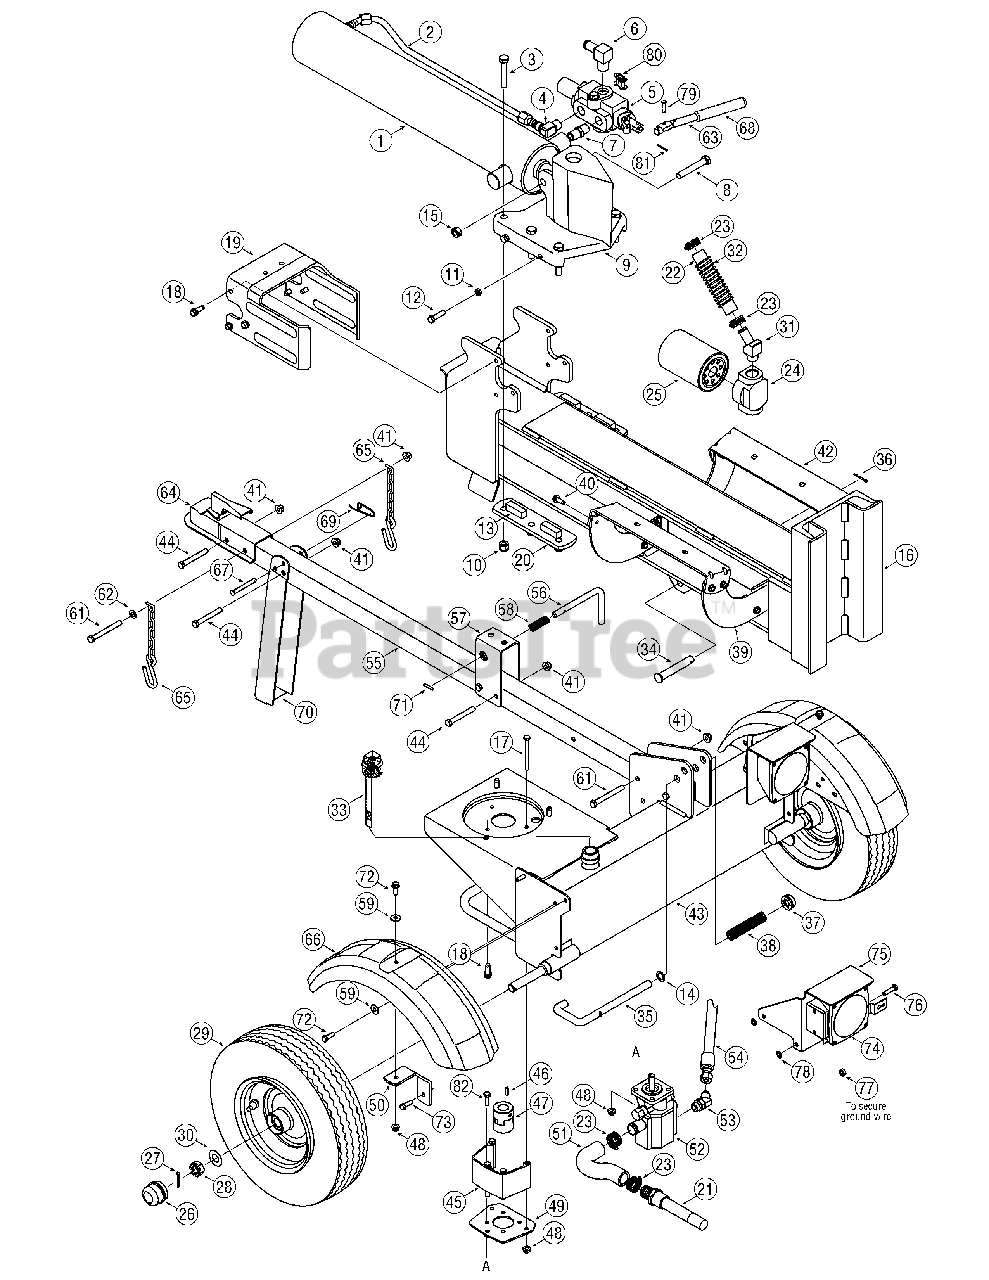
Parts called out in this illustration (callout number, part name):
1	Hydraulic Cylinder 718-0769A
1	Kit Seal 4.5" for XINGHUI cylinder 718-0769A
1	Kit Seal 4.5" for ENERGY cylinder 718-0769A
2	Hydraulic Tube
3	Hex Cap Screw 1/2-20 x 2.75
4	90 Degree Solid Adapter
5	Control Valve
6	Return Elbow
7	Nipple Pipe 1/2-14
8	Hex Cap Screw 1/2-13 x 3.25
9	Wedge Assembly
10	Hex Lock Nut, 1/2-20
11	Hex Jam Nut 3/8-24
12	Hex Cap Screw 3/8-24 x 1.5
14	Flat Washer.635 x.93 x.06
15	Hex Lock Nut 1/2-13
16	Beam Assembly
17	Hex Screw, 5/16-18 x 3.25
18	Hex Washer Screw 3/8-16 x 1.0
19	Dislodger Bracket
20	Back Plate
21	Inlet Filter
22	Return Hose 3/4" ID x 44" Lg.
23	Hose Clamp 5/8"
24	Filter Housing
25	Oil Filter
26	Hub Cap
27	Cotter Pin
28	Slotted Nut 3/4-16
29	Wheel Assembly
29	Cone Bearing
29	Grease Retainer
30	Flat Washer.760 ID x.500 OD
31	Adapter 3/4-14
32	Hose Guard
33	Vented Dipstick
34	Clevis Pin
35	Lock Rod
36	Cotter Pin
37	Push Cap
38	Compression Spring
39	Log Tray Bracket
40	TT Screw, 5/16-18 x.875
41	Flange Lock Nut, 3/8-16
43	Frame Assembly
44	Hex Bolt 3/8-16 x 3"
45	Coupling Shield
46	Square Key 3/16" x.75
47	Flexible Coupling
48	Flange Lock Nut, 5/16-18
49	Rear Coupling Support Bracket
50	Fender Mounting Bracket
52	Gear Pump
53	45 Degree Elbow Fitting
54	High Pressure Hydraulic Hose
55	Tongue Assembly
56	Latch Rod
58	Compression Spring
59	Flat Washer
60	Hose Guard
61	Hex Cap Screw, 3/8-16 x 3.50
62	Flat Washer,.375 x.738 x.063
63	Hydraulic Valve Control
64	Hitch Coupling Assembly
66	Fender
67	Clevis Pin
69	Spring Pin
70	Jack Stand
71	Spiral Pin
72	TT Screw, 5/16-18 x 0.875"
73	TT Screw, 5/16-18 x 1.00
74	Light Kit
75	Light Bracket - LH
75	Light Bracket - RH
76	Screw, 5/16-18 x 1.25
77	Jam Nut, 3/8-16
78	Speed Nut, .3125 ID
79	Clevis Pin
80	Valve Handle Link
81	Cotter Pin
82	Hex Screw, 5/16-18 x 1.00
